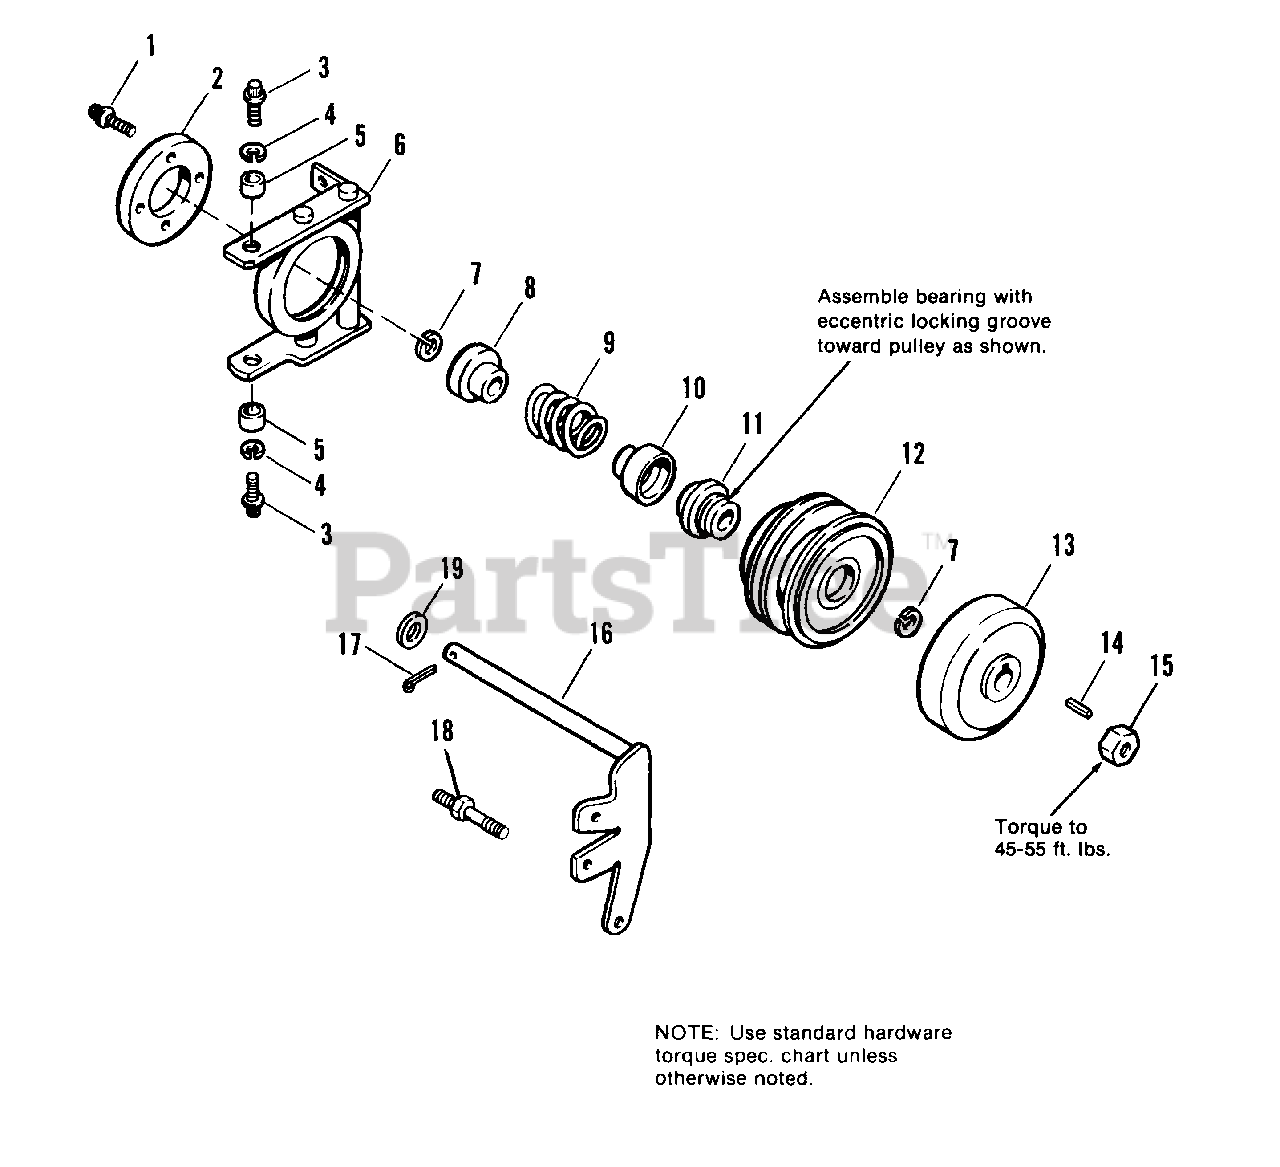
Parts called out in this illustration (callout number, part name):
1	CAPSCREW, Socket Hd., 1/4-20 x 5/8
2	DISC, Brake
3	SCREW, Thd. Forming
4	LOCKWASHER, 5/16
6	PIVOT ASSY.
7	RING, Retaining
8	GUIDE, Spring
10	GUIDE, Spring
11	BEARING ASSY.
13	PLATE ASSY., Clutch
14	KEY
15	LOCKNUT, Hex, 3/4-16
16	ARM ASSY., Pivot
17	PIN, Cotter, 3/16 x 1-1/2
